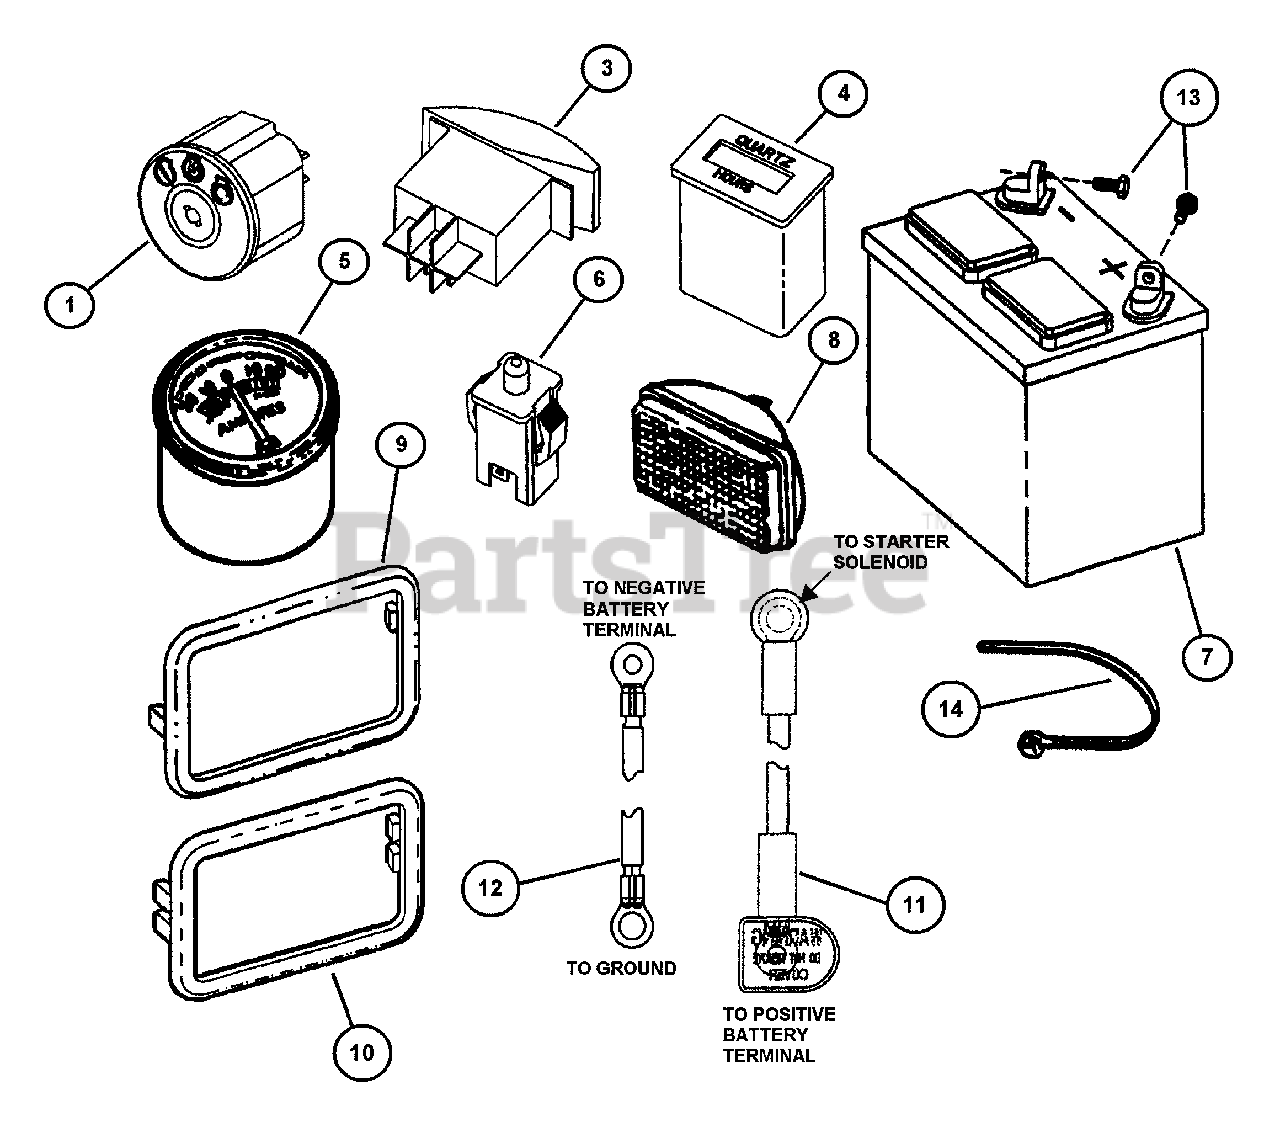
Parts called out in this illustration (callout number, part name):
1	SWITCH, IGNITION
3	SWITCH, LIGHTS
4	HOURMETER, HOBBS SNAP-IN
5	AMMETER AND CLAMP ASM
6	SWITCH, DP NO/NC SNAP-IN
7	BATTERY, 11 PLATE 375CCA
8	HEAD LIGHT
9	BEZEL, Headlight
10	BEZEL, HEADLIGHT
11	CABLE, POSITIVE BATTERY (47" long)
12	CABLE, NEGATIVE BATTERY (23" long)
13	HWST,10-24X.50 SEMS
14	WIRE TIE, 11 INCH STD BLK NYLON
